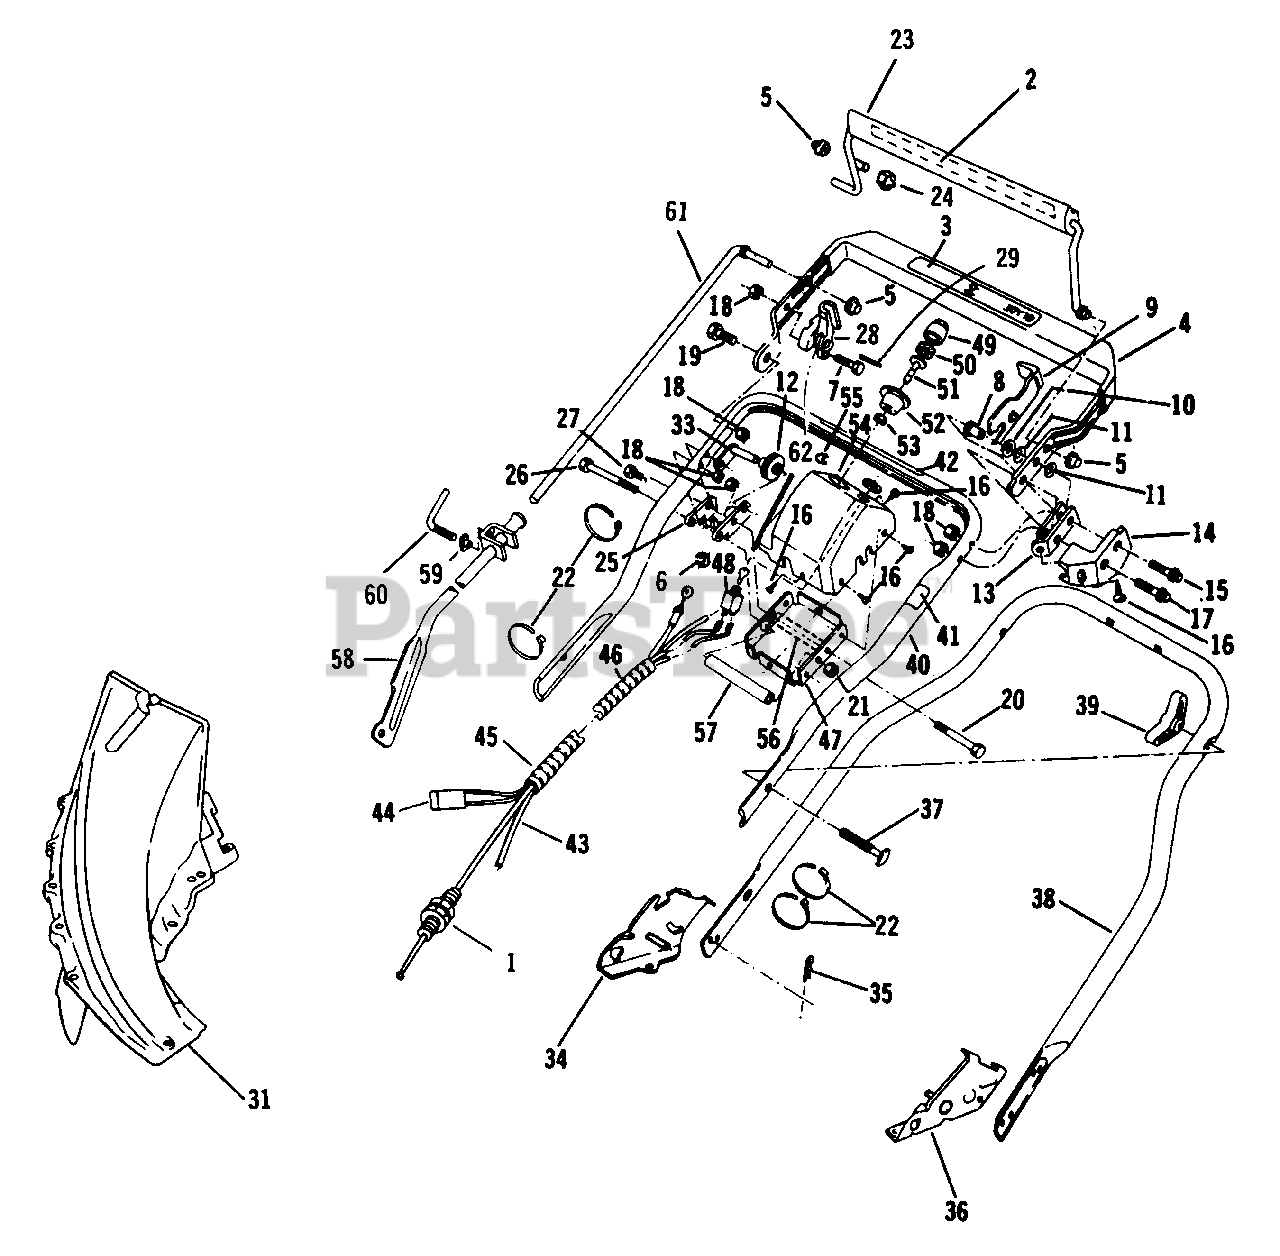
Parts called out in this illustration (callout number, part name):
1	Control Cable Assembly
2	Decal-Blade Control
3	Decal-Drive Control
4	Top Handle and Grip Assembly
5	Pushnut
6	Ring-Retainer
7	Bolt-Hex
8	Spacer-Flanged
9	Lever-Lockout
10	Washer-Plain
11	Washer-Spring
12	Pulley
13	Down-Stop
14	Guard-Lockout
15	Bolt-Shoulder
16	Screw
17	Bolt-Shoulder-L.H.
18	Locknut
19	Bolt-Shoulder-R.H.
20	Screw-Hex Hd. Cap
21	Nut-Hex Jam
22	Tie Strap
23	Control Lever and Nut Assembly
24	Nut-Acorn
25	Bracket-Clutch Cable
26	Screw
27	Screw-Clutch Cable Brkt.
28	Cam and Roll Pin Assembly
29	Roll Pin
31	Chute Assembly
33	Pivot-Bracket Pulley
34	Bracket-Handle-R.H.
35	Hair Pin
36	Bracket-Handle-L.H.
37	Screw
38	Handle Section-Bottom
39	Knob
40	Handle Section-Center
41	Decal-Drive Lockout
42	Decal-Starting Inst.
43	Tubing-Primer
44	Wire Harness Assembly
45	Spiral Tubing
46	Spiral Tubing
47	Plate-Cover Assembly
48	Switch Assembly
49	Primer Bulb
50	Filter
51	Primer Base
52	Cup
53	Locknut
54	Cover
55	Decal
56	Spacer
57	Spacer
58	Control Lever Assembly
59	Nut-Control Lever Clamp
60	Lever-Rod Clamp
61	Rod-Control
62	Kev Switch (2)
